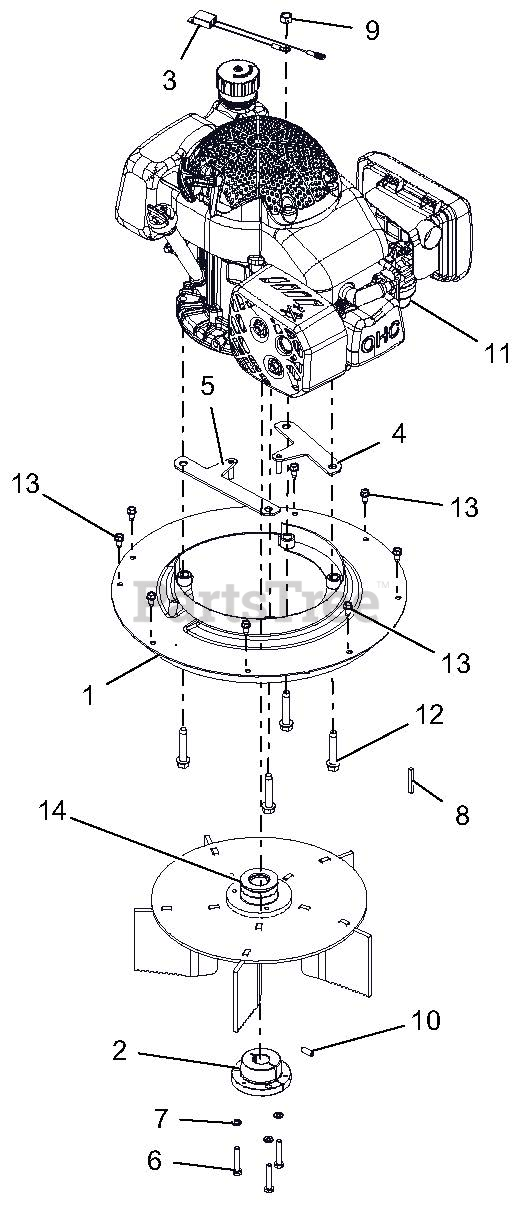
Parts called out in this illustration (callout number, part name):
1	WMT-ENGINE PLATE
2	BUSHING, TAPER-SPLIT 7/8"(SDS)
3	WIRE HARNESS-APV
4	WLDMT, BRKT - APV BELT FNGR L
5	WLDMT, BRKT - APV BELT FNGR R
6	BLT-HEX .25-20X1.5 FTHD GR5 ZC
7	@WSHR-LK .25X.062 REG YWZC
8	KEY-SQ .188X1.50X.188
9	@NUT-LK-CTR .38-16 YWZC
10	SCR,SET .25-20X.75 PCPT SH
11	ENGINE,SUBARU EA190 (CARB)
12	SCR-TAP .38-16X2.00 HWH TR YZ
13	SCR-TAP .25-20X.50 HWH TR YWZ
14	WLDMT, IMPELLER - APV TAPER
